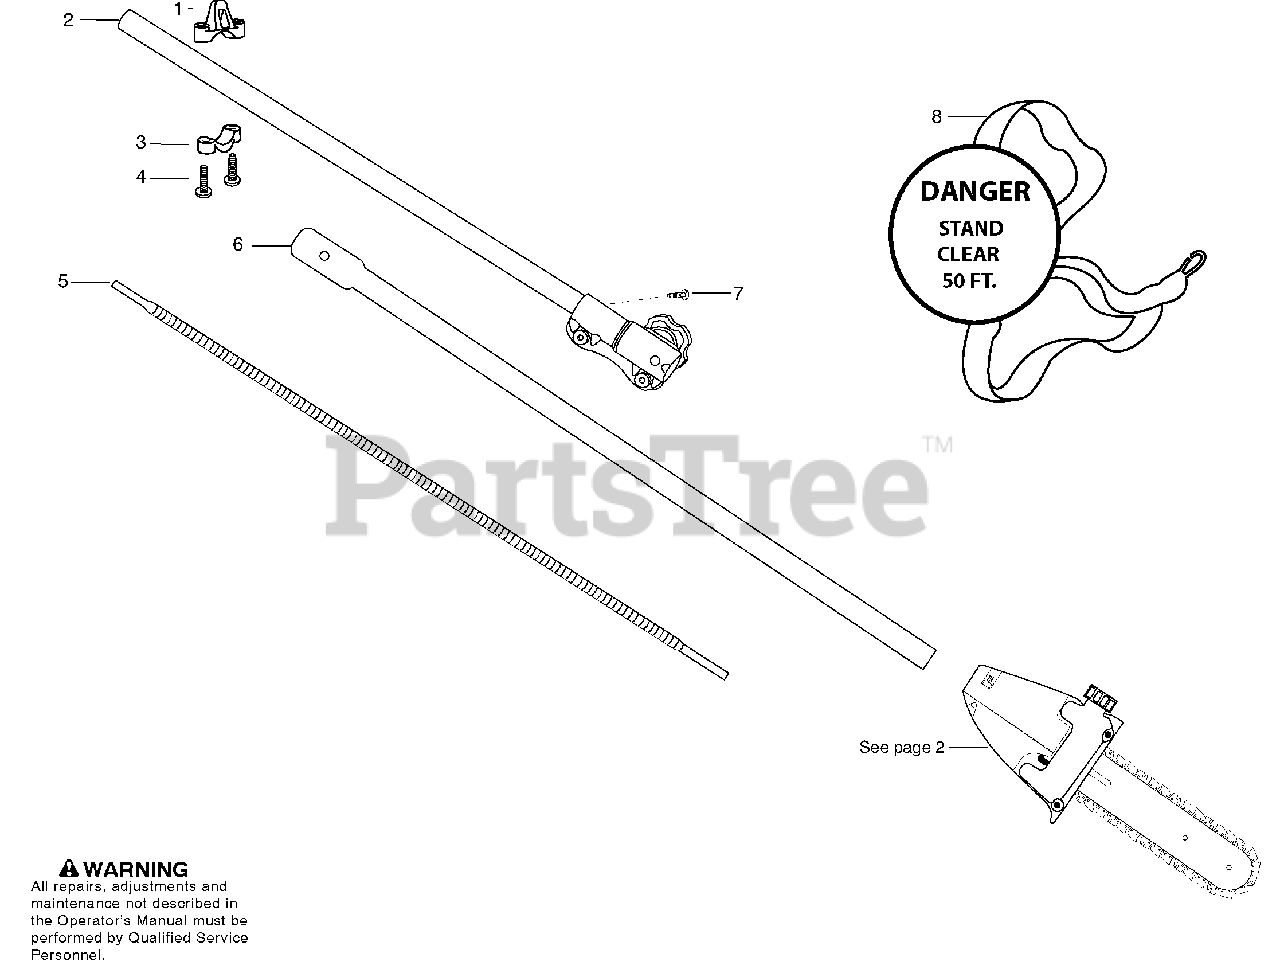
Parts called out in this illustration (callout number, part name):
1	Clamp - Harness Upper
2	Assy. - Middle Shaft
3	Clamp - Harness Lower
4	Screw (#10 plastite)
5	Flexshaft - Lower
6	Assy. - Lower Shaft
7	Screw (12-24 x .480)
8	Strap - Shoulder
